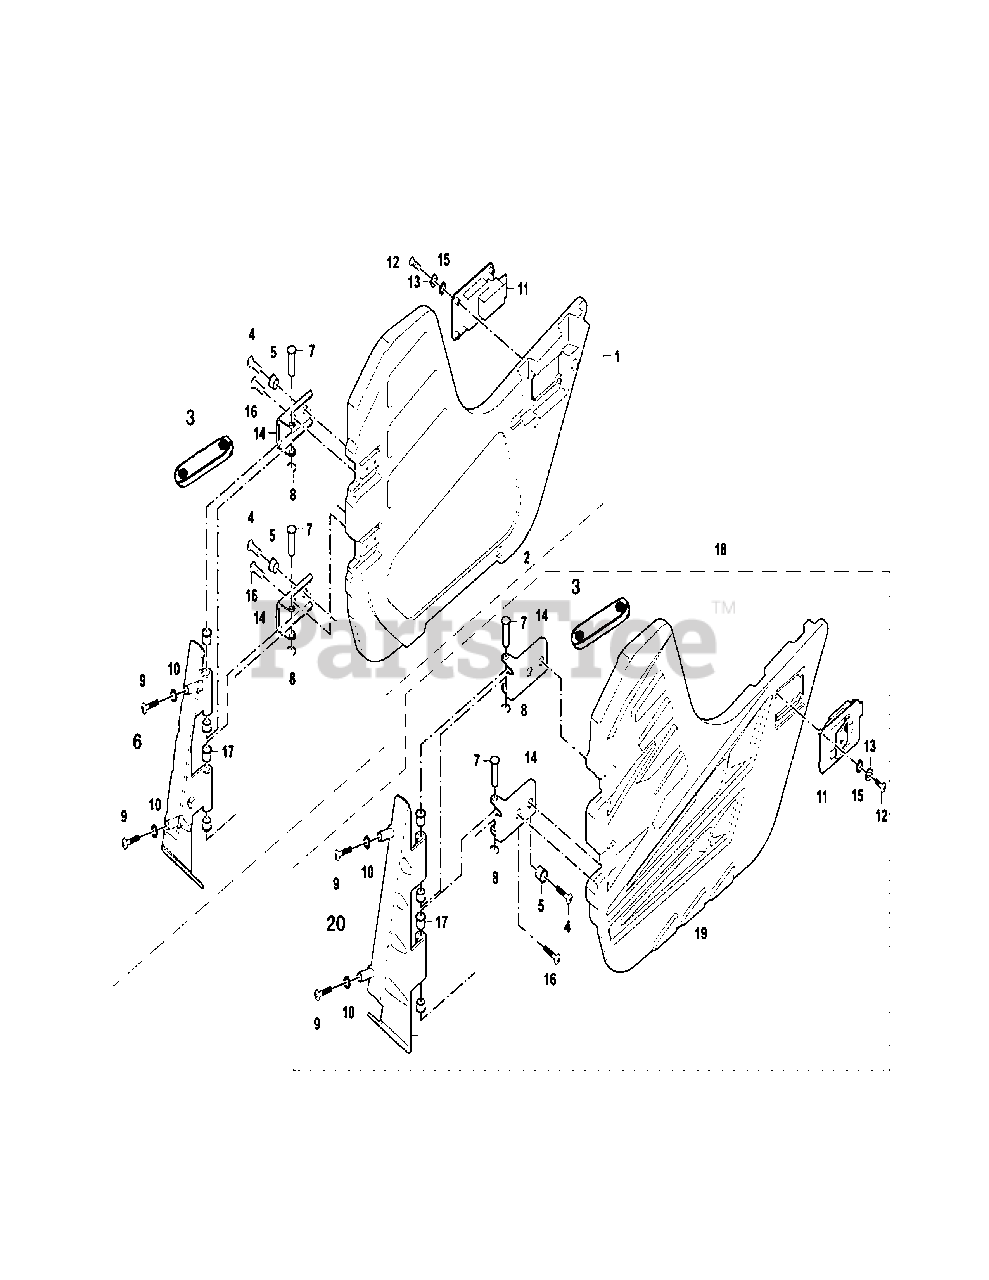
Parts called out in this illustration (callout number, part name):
1	Right Door Comp.
2	Right Door
3	Position Return Band III
4	Cross large plate head screw M6×16
5	Bushing 6.5×9×22×6.5
6	Right Door Mounting Bracket
7	Pin 10×17×44
8	Split Washer 8×1
9	Hexagon Socket Head Bolt M8×22-10×16
10	Curved Washer
11	Right Side Door Locker
12	Screw M5×8
13	Spring Gasket-5
14	Side Door Gemel
15	Wasger5×12×1
16	Cross Large Plate Head Screw M6×12
17	Nylon Bushing IV
18	Left Door Comp.
19	Left Door
20	Left Door Mounting Bracket
